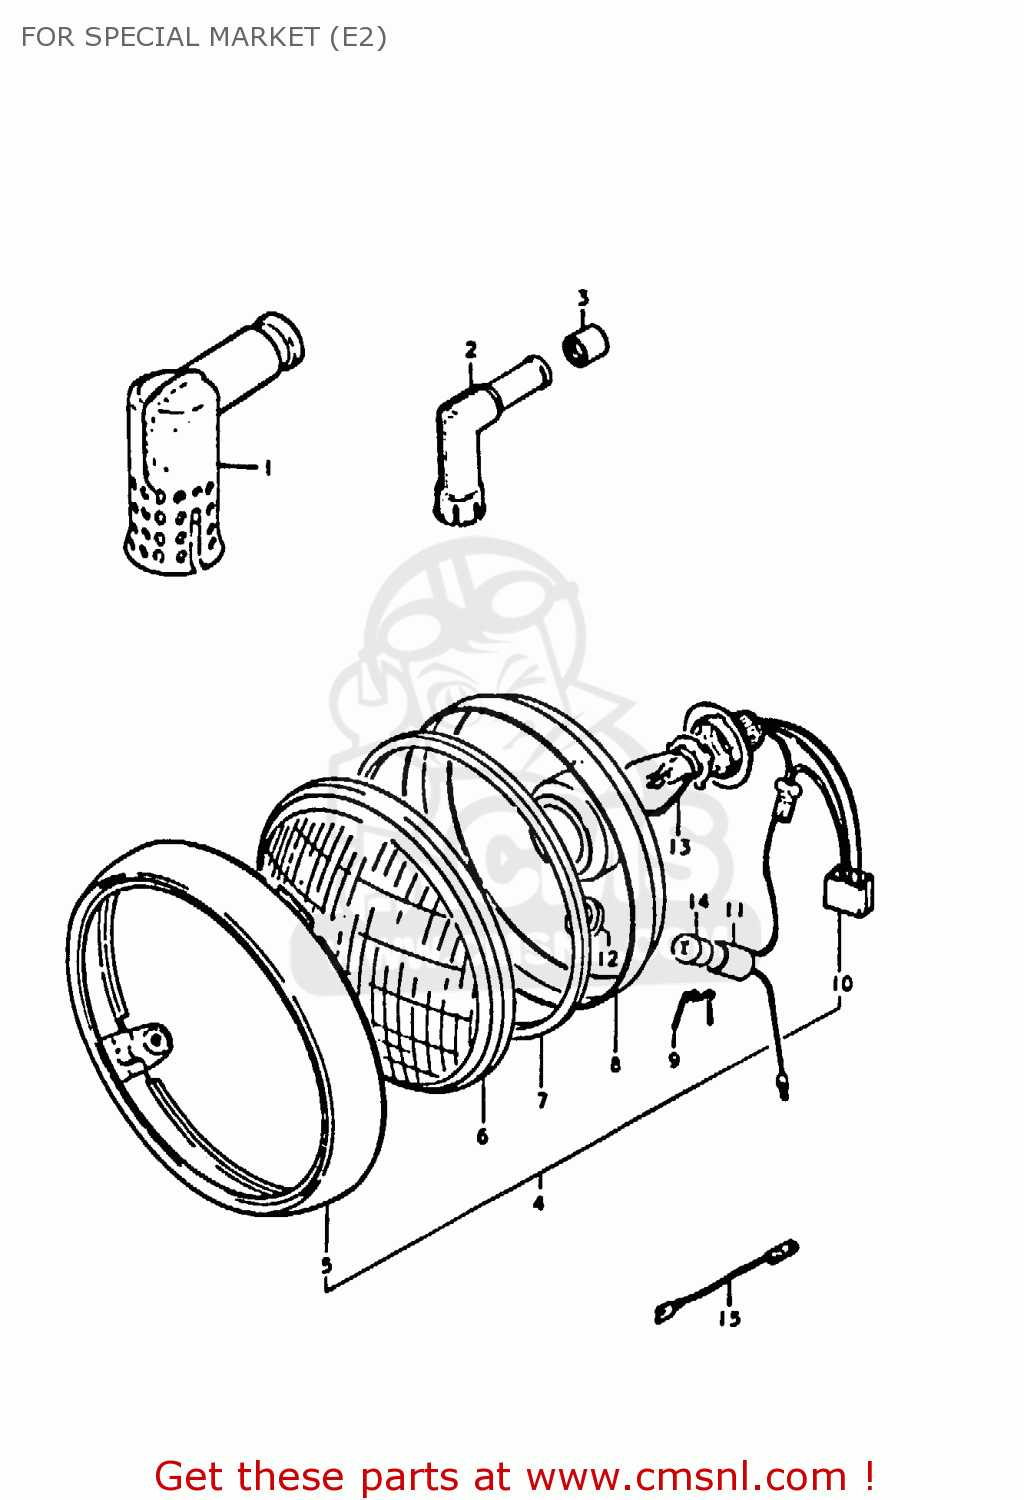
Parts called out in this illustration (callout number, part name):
1	PISTON
2	CAP,SPARK PLUG
3	PIN,PISTON 14MM
4	RING,SNAP 14MM
5	BEARING
6	CRANKSHAFT ASSEMBLY
7	CONNECTING ROD
8	WASHER(19X32X1)
9	PIN,CRANK
10	BEARING
11	CRANKSHAFT
12	CRANKSHAFT,LEFT
13	THRUST WASHER
14	SPACER
15	OIL SEAL
16	BEARING
17	Bearing
18	BEARING(20X52X15)
19	OIL SEAL (25X44X7)
20	VALVE,ROTARY
21	GUIDE,ROTERY VALVE
22	PIN 3X5
23	SEAT,CRANKCASE OUTER VALVE
24	O RING(D:1.5,ID:22.5)
25	O-RING (D:1.5 ID:10)
26	O RING(D:2,ID:99)
27	SEAT,ROTERY VALVE INNER
28	GASKET,ROTERY VALVE INNER SEAT (NAS)
29	SCREW
30	SCREW
31	PLATE,CSHAFT OIL GUIDE
32	GEAR,PRIMARY DRIVE
33	SPACER(20X25X10)
34	NUT
35	WASHER
36	KEY 4MM
37	KEY
